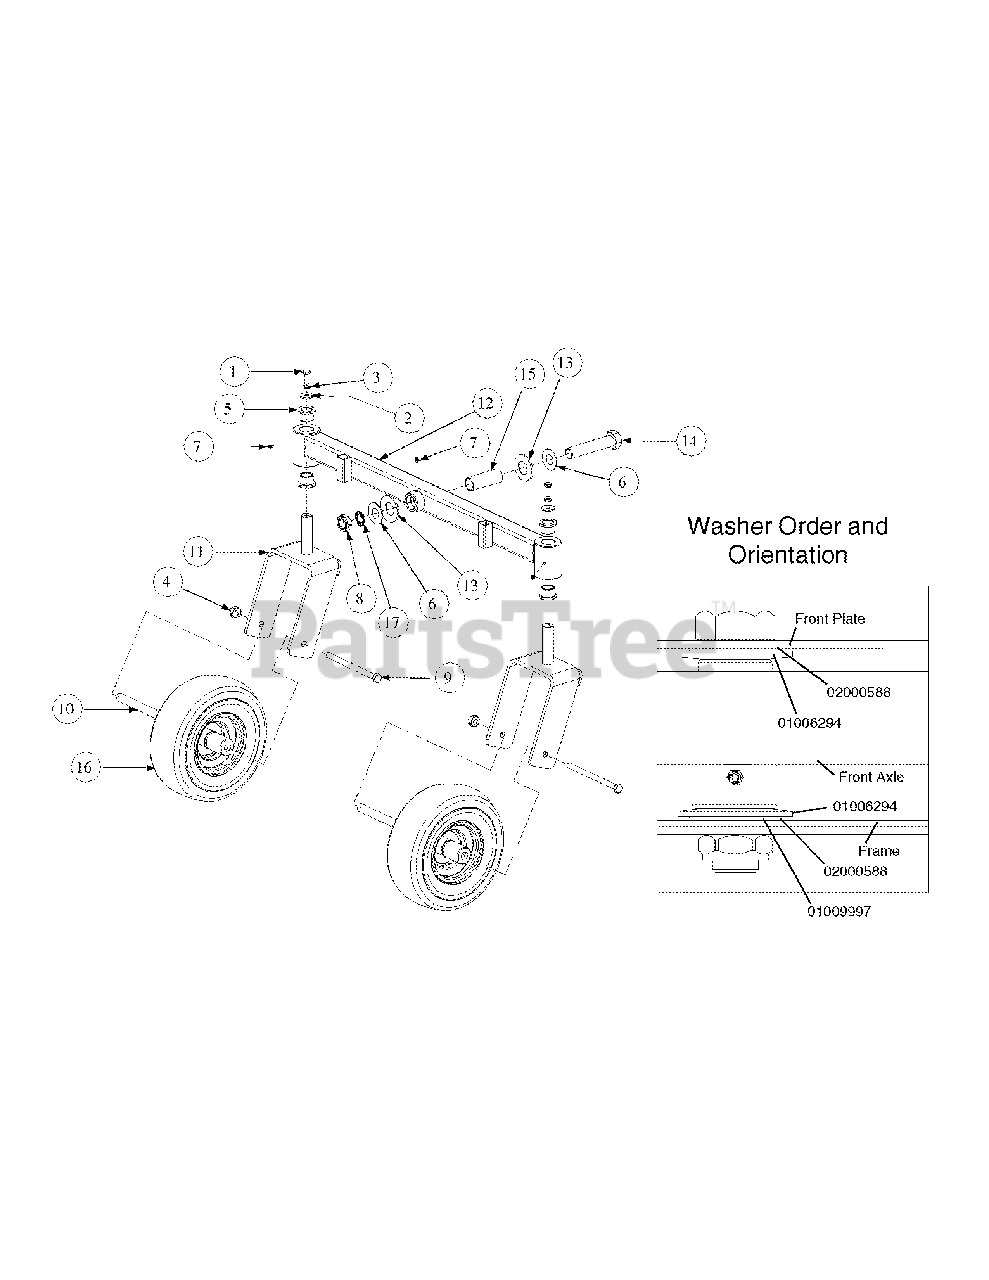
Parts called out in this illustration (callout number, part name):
1	Hex Cap Screw, 3/8-16, x 1
2	Flat Washer, .411 x 1.25 x 1.00
3	Lock Washer, 3/8
4	Center Lock Nut, 1/2-20
5	Flange Bearing, 1.013
6	Flat Washer, 1.00 ID x 2.00 OD x .075
7	Grease Fitting, 1/4-28 x 3/16
8	Jam Lock Nut, 1.0-14
9	Hex Cap Screw, 1/2-20 x 7.00
10	Spacer, .51 ID x .75 OD x 5.83 Lg
11	Caster Wheel Bracket Assembly
12	Narrow Front Axle Assembly
13	Belle Washer, 1.25 ID x 2.500 OD x .1
14	Hex Cap Screw, 1-14 x 5.0
15	Spacer, 1.005 ID x 1.25 OD x 3.6
16	Wheel Assembly, 11 x 4-5.00
17	Retainer Extension, Self Locking
